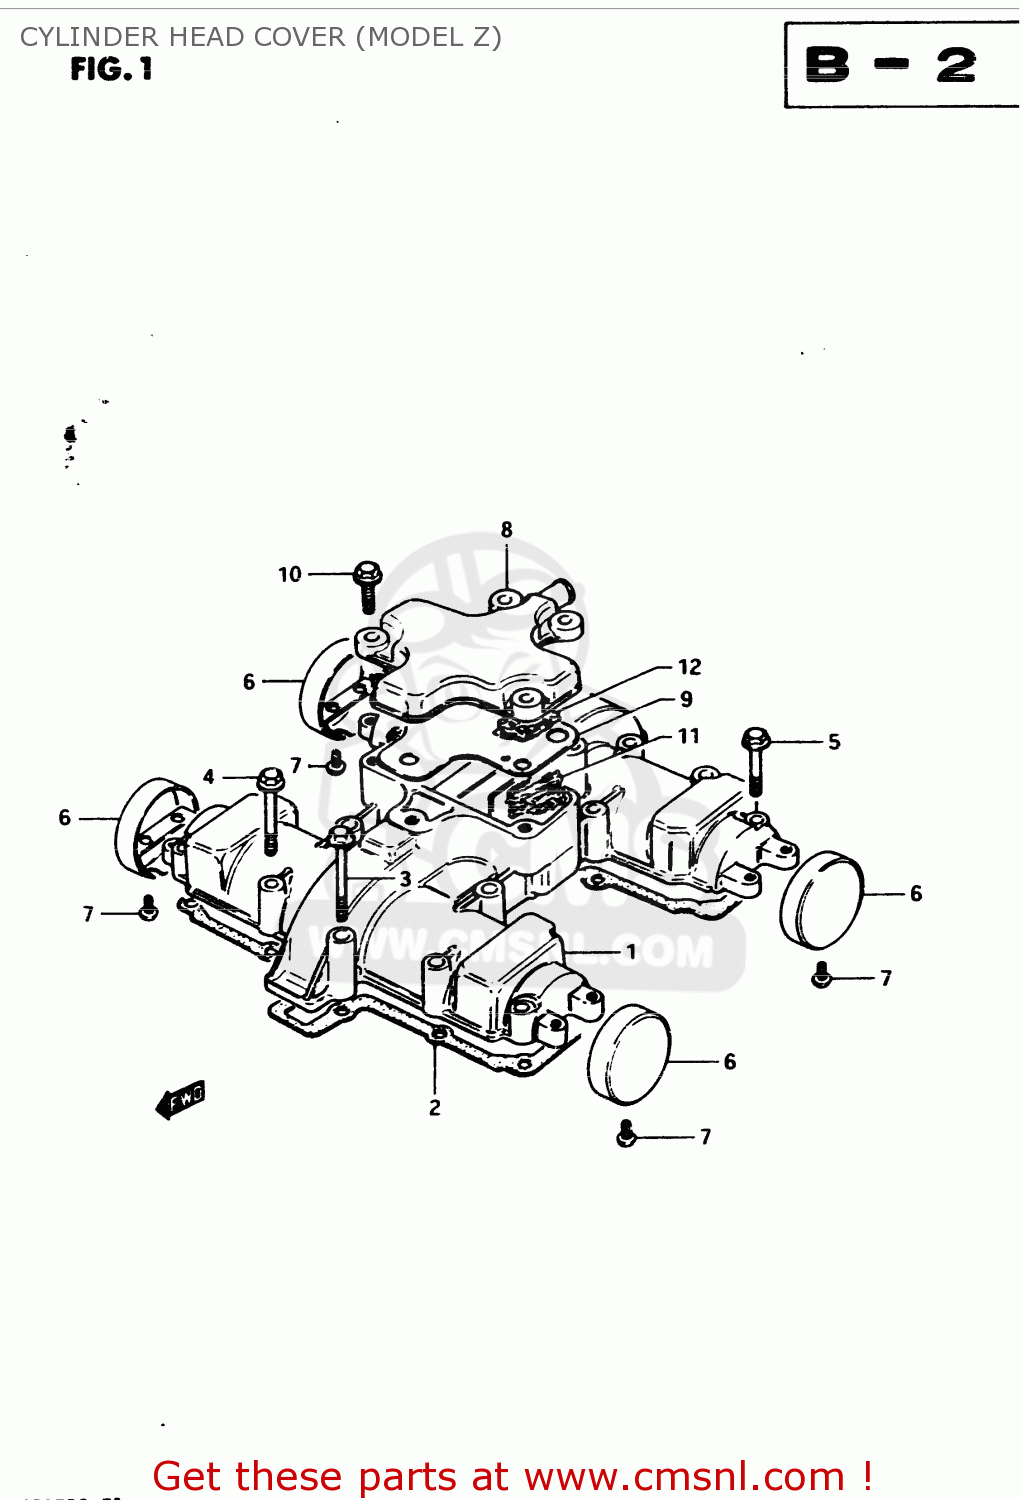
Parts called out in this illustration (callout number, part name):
1	COVER,CYLINDER HEAD
2	GASKET,CYLINDER HEAD COVER (MCA)
3	BOLT,UNDER
4	BOLT
5	BOLT
6	CAP,CYLINDER HEAD COVER
7	SCREW
8	COVER,BREATHER
9	GASKET (MCA)
10	BOLT,REAR
11	COVER,BREATHER
12	SEPARATOR,OIL BREATHER
